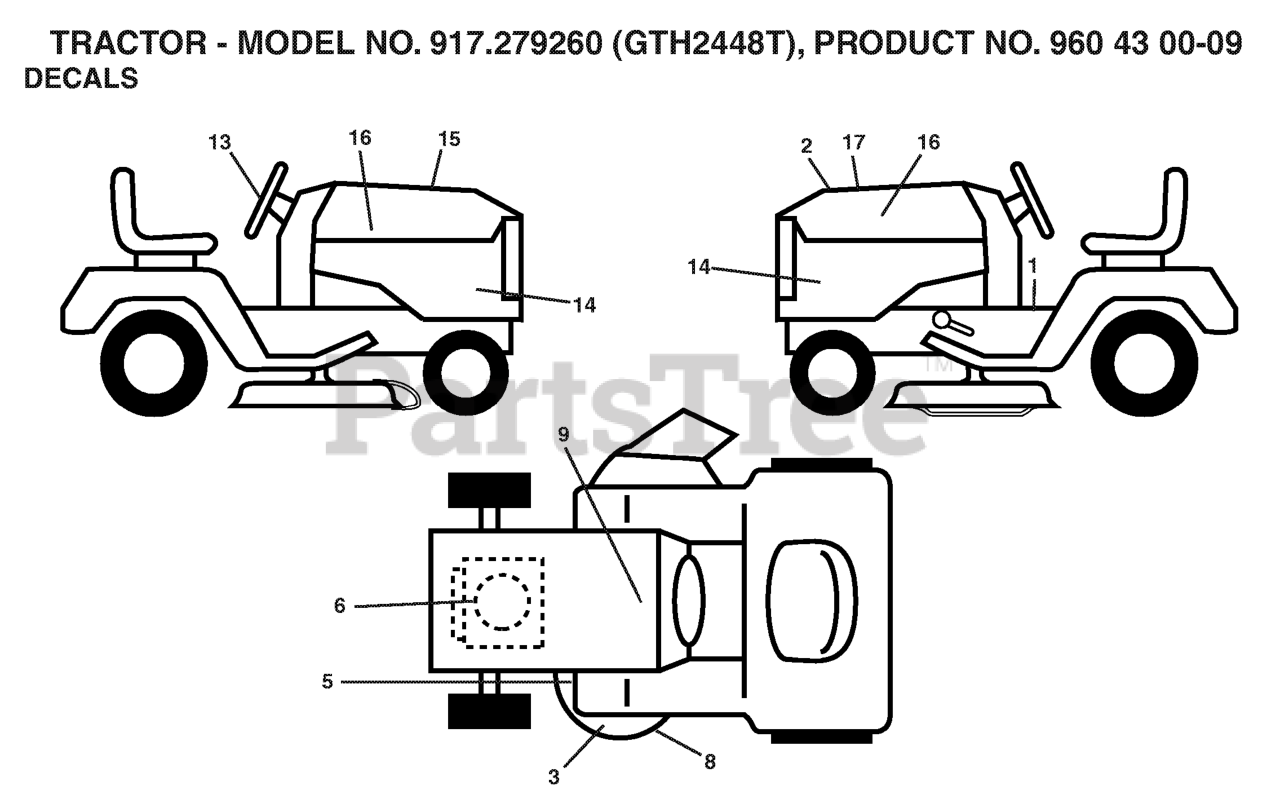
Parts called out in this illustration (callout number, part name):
1	DECAL.FEND.INS/WARN.HY
2	DECAL.HOOD.TOP.INSERT.
3	DECAL.WARN.KEEP.HAND.AWAY
5	DECAL CLUTCH/BRAKE
6	DECAL.ENG.B&S.24
8	DECAL.MOWER.SCH.48/54
9	DECAL BTRY SYMBOLS
13	DECAL.WHEEL.STRG.LGN.H
14	DECAL.PANEL.SIDE.GTH2448T
15	DECAL HOOD CUST. RESP.
16	DECAL.HOOD.NAMELOGO.HUSQ
17	DECAL.REPLACEMENT.GTH2448T.
